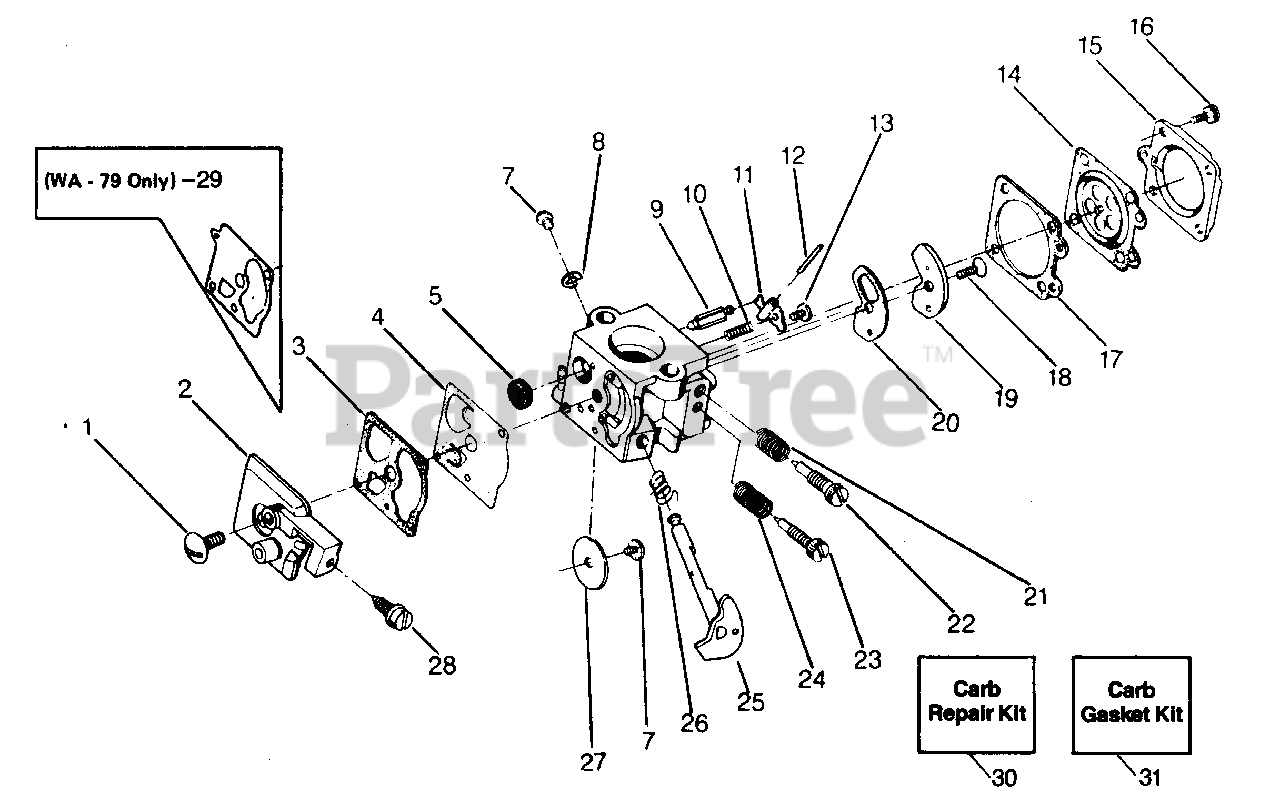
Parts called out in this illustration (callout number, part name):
1	Screw - Pump Cover
2	WA-149 (#35183)
3	Gasket - Pump
3	WA-149 (#35183)
4	Diaphragm - Pump
4	WA-149 (#35183)
5	Screen-Inlet
7	Screw - Throttle Shaft
8	Clip - Throttle Shaft
9	Valve - Inlet Needle
10	Spring - Metering Lever
11	Lever - Metering
12	Pin - Metering Lever
13	Screw - Metering Lever Pin
14	Diaphragm Assembly - Metering
15	Cover - Metering Diaphragm
16	Screw Assembly - Metering Cover & Throttle Shaft Clip
17	Gasket - Metering Diaphragm
18	Screw - Circuit Plate
19	Plate - Circuit
20	Gasket - Circuit Plate
21	Spring - Hi Speed Needle
22	Needle - Hi Speed
23	Needle - Idle
24	Spring - Idle Needle
25	Shaft Assembly - Throttle
26	Spring - Throttle Return
27	Valve - Throttle
28	Screw - Idle Adjustment
29	Diaphragm - Pump (WA-79 only)
30	Kit - Carb. Kwik Repair
30	WA-149 (#35183)
31	Kit - Carb. Gasket/Diaphragm
31	WA-149 (#35183)
